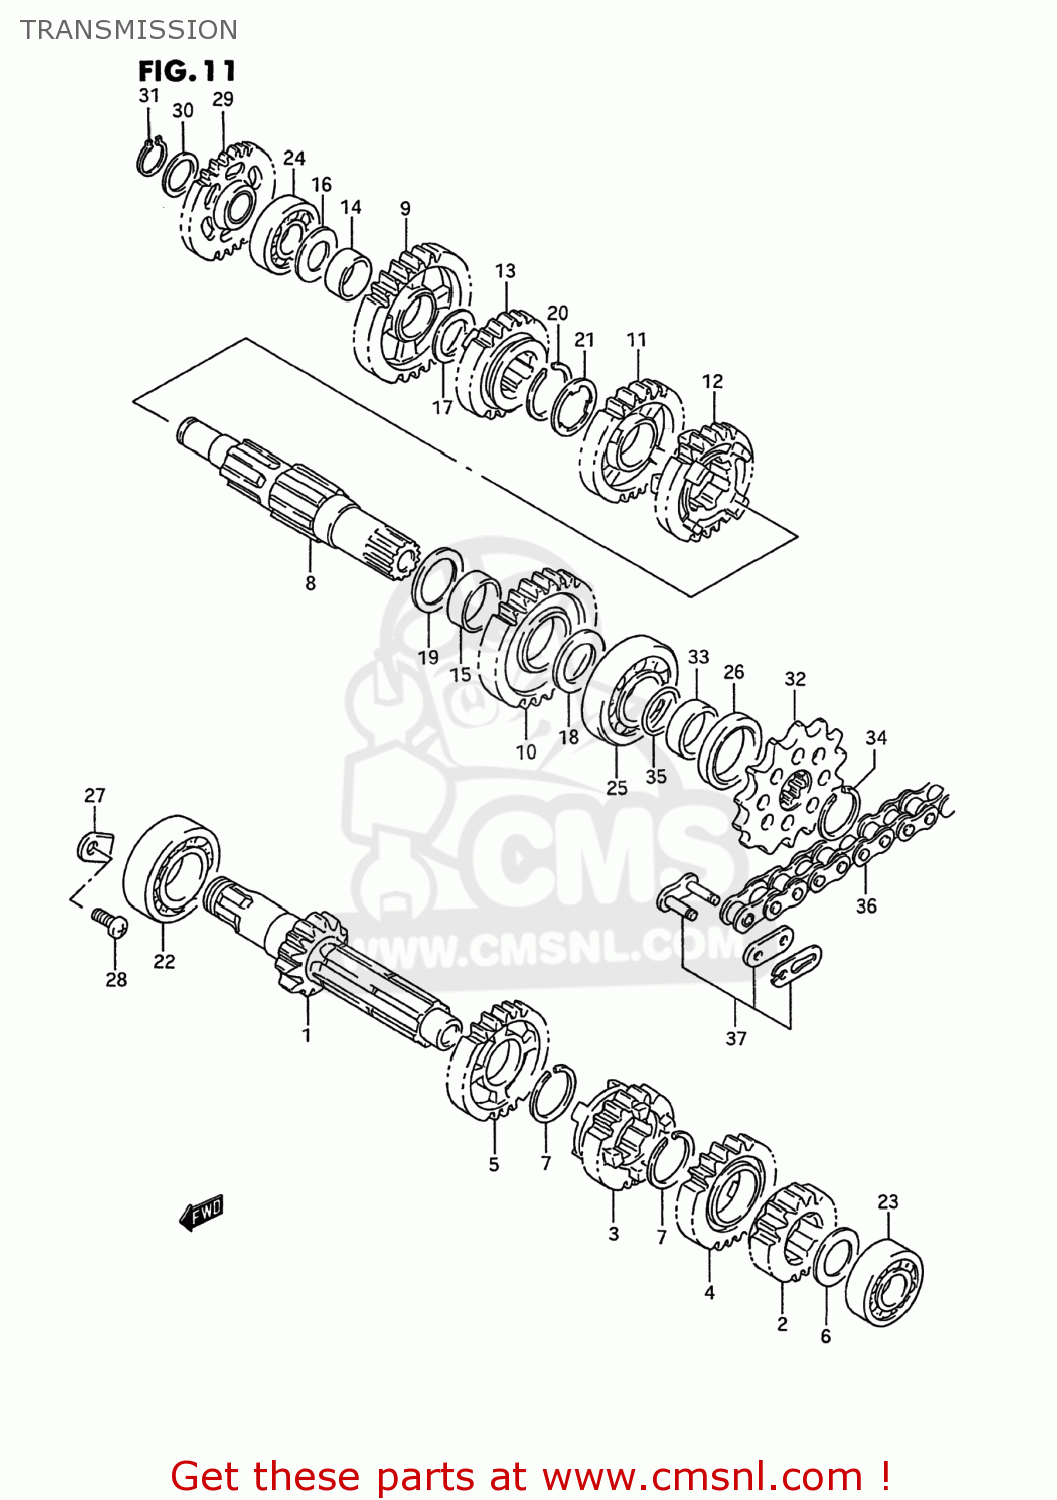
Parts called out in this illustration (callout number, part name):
1	SHAFT,COUNTER
2	GEAR,SECOND DRIVE (NT:17)
3	GEAR,3RD DRIVE
4	GEAR,4TH DRIVE(NT:19)
5	GEAR,FIFTH DRIVE
6	WASHER,THRUST
7	CIRCLIP
8	SHAFT,DRIVE
9	GEAR,1ST DRIVEN
10	GEAR,2ND DRIVEN(NT:29)
11	GEAR,THIRD DRIVEN
12	GEAR,4TH DRIVEN(NT:22)
13	GEAR,5TH DRIVEN(NT:23)
14	BUSH(20X24X10)
15	BUSH(25X28X10)
16	WASHER,THRUST
17	WASHER
18	WASHER
19	WASHER
20	CIRCLIP
21	WASHER,LOCK
22	BEARING
23	BEARING(17X40X12)
24	BEARING(17X40X12)
25	BEARING(22X56X15)
26	SEAL,OIL(28X38X6)
27	RETAINER
28	SCREW
29	GEAR,KICK STARTER IDLE
30	SHIM
31	CIRCLIP
32	SPROCKET,ENGINE
33	SPACER,ENGINE SPROCKET
34	CIRCLIP
35	O RING(D:1.9,ID:21.8)
36	CHAIN,DRIVE(520KD2X116LE)
37	JOINT ASSEMBLY,CHAIN
